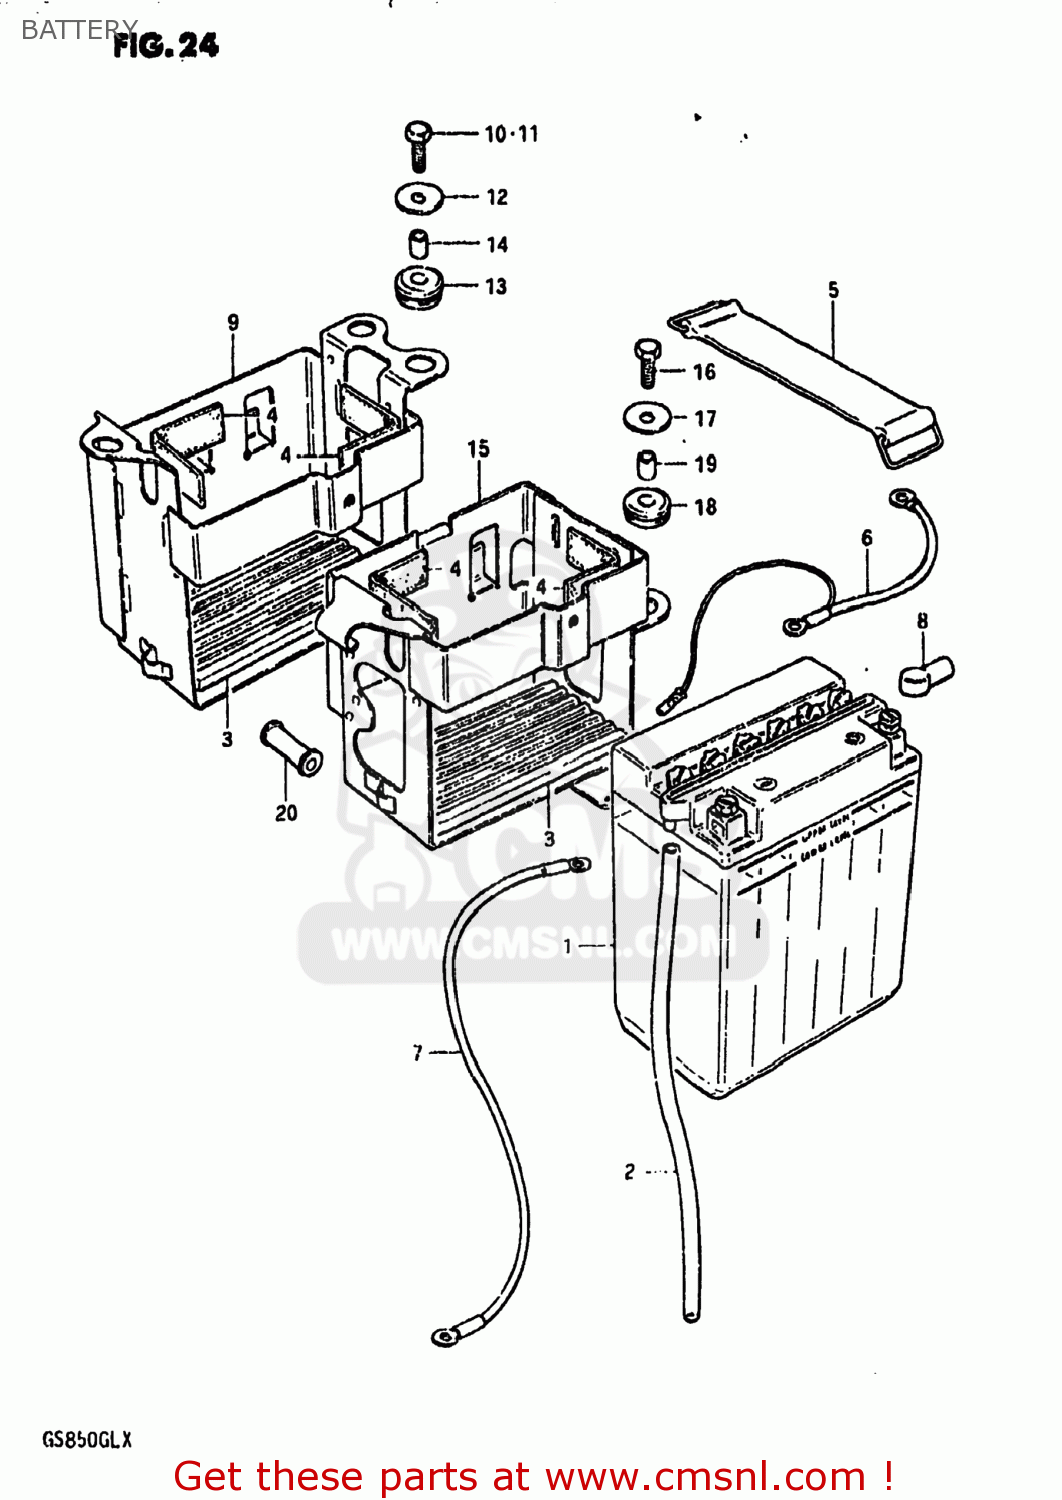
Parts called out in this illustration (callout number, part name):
1	BATTERY ASSY (12V)
2	HOSE,BATTERY EXHAUST
3	PROTECTOR,BATTERY
4	PROTECTOR(20X90)X4
5	BAND
6	WIRE,BATTERY PLUS
7	LEAD WIRE,BATTERY(-)
8	CAP,TERMINAL
9	HOLDER,BATTERY
10	BOLT
11	BOLT, UPPER
12	WASHER(6,5X22X1.6)
13	CUSHION
14	SPACER(6.2X8.3X5.7)
15	HOLDER,BATTERY
16	BOLT, UPPER
17	WASHER(6,5X22X1.6)
18	CUSHION
19	SPACER(6.2X8.3X5.7)
20	CUSHION
